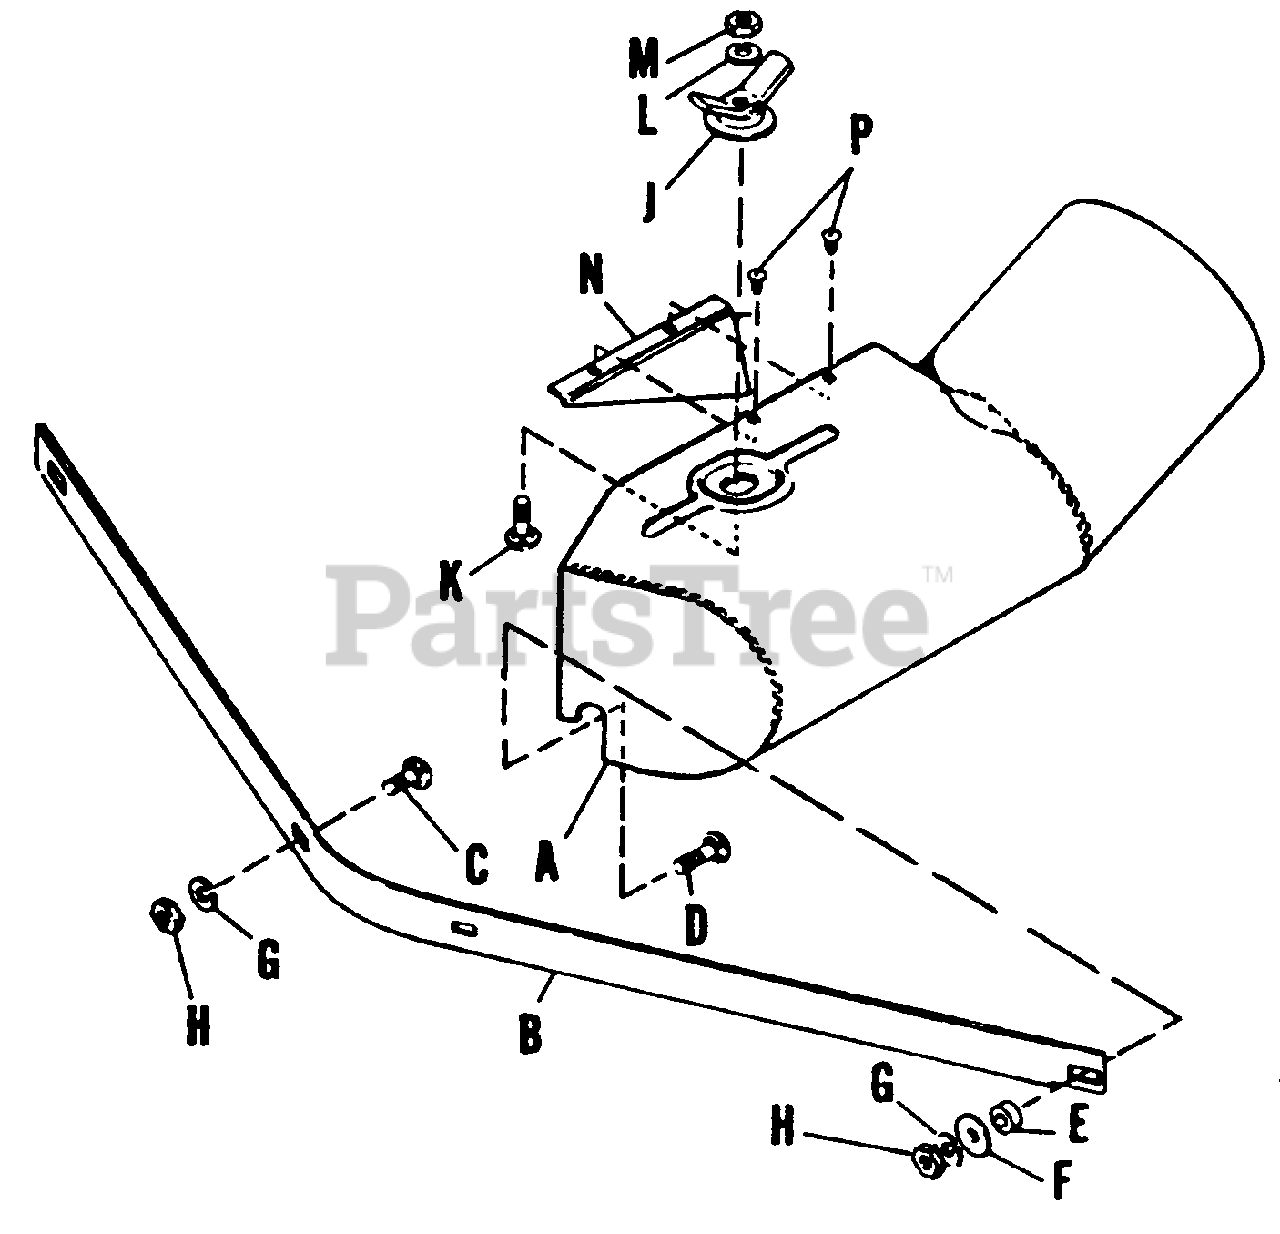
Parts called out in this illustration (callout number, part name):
A	Collector Side Housing Assy.
B	Front Baffle
C	Carriage Bolt, 3/8"-16 x 1"
D	Carriage Bolt, 3/8"-16 x 1 1/4"
G	Lock Washer, 3/8"
H	Nut, Hex, Full, 3/8"-16
J	Nut Assembly
K	Carriage Bolt, 3/8"-16 x 1"
L	Lock Washer, 3/8"
M	Nut, Hex, Full, 3/8"-16
P	Screw, Self Tapping, No. 10-24 x 1/2"
